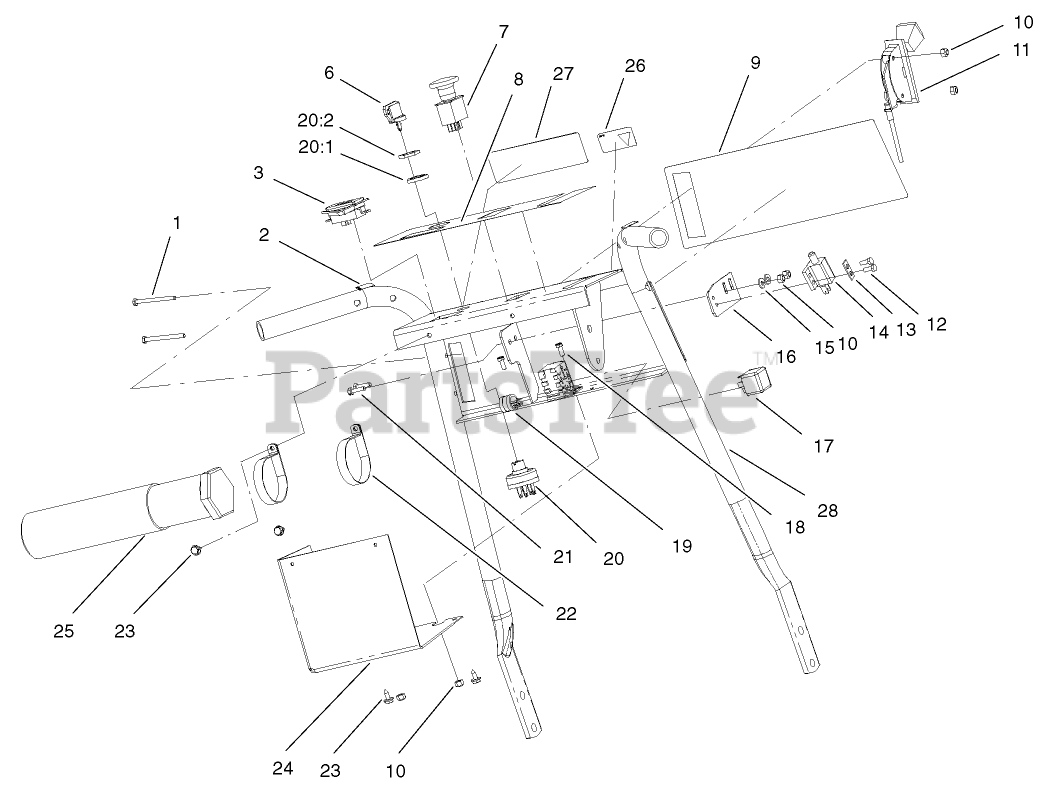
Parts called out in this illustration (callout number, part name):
1	SCREW-SHH
2	DECAL-LOCK, NEUTRAL
3	HOURMETER
6	KEY-IGNITION
7	SWITCH-PTO
8	Decal-Warning
9	DECAL-PROLINE
10	NUT-LOCK, NI
11	CONTROL-THROTTLE
12	SCREW-TAPTITE
13	PLATE-SWITCH
14	SWITCH-POLE, SINGLE
15	WASHER-FLAT
16	PLATE-MOUNTING, SWITCH
17	RELAY
18	SCREW-HWH
19	CLAMP-R
20	Key Switch ASM
20:1	WASHER-TOOTH, INTERNAL
20:2	NUT-HH
21	SCREW-HWH
22	CLAMP-R
23	SCREW-HWHTF
24	BRACKET-COVER
25	TUBE-MANUAL
26	DECAL-PROTECTION, EAR
27	DECAL-WARNING
28	Handle ASM
